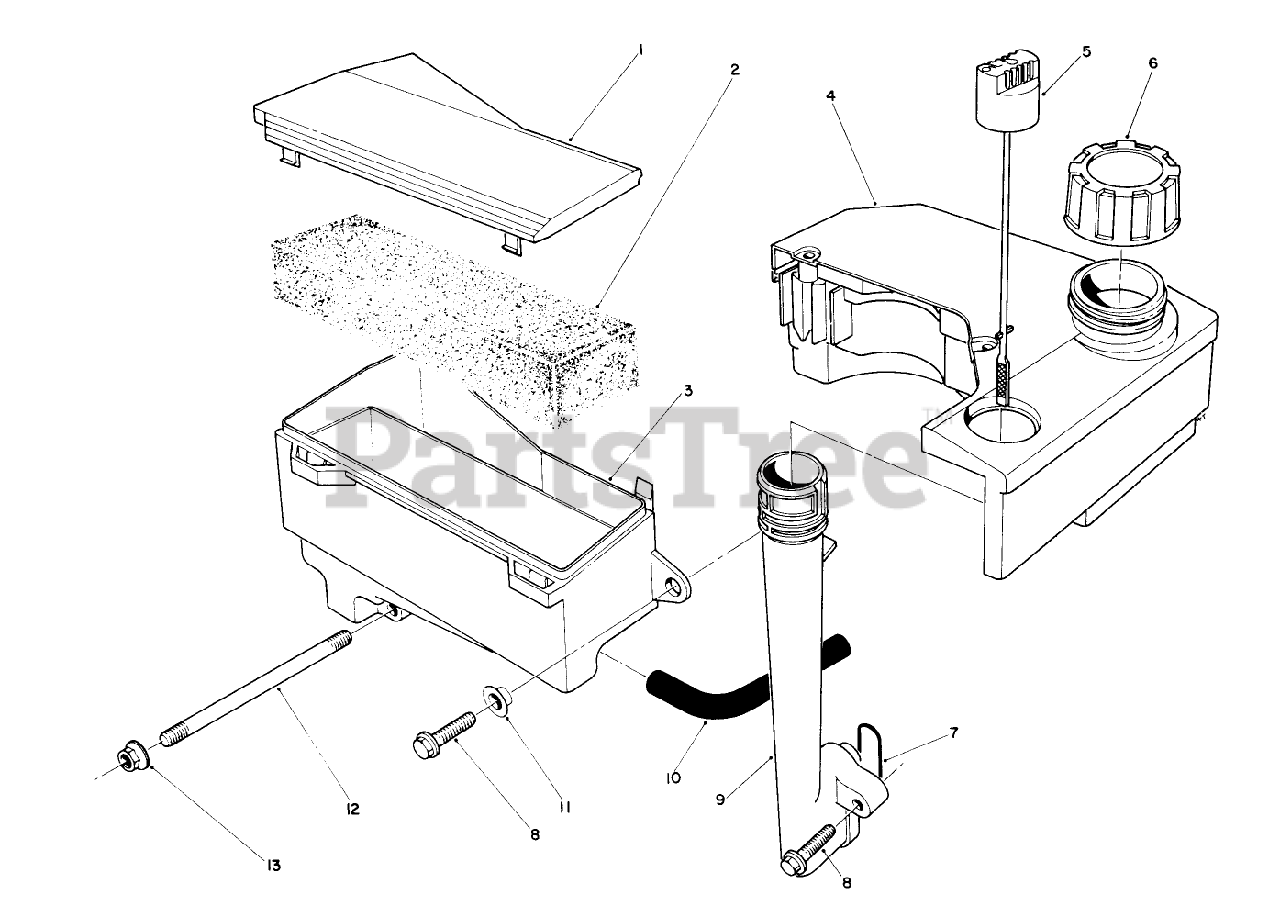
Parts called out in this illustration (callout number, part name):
1	AIR CLEANER CAP
3	Body-Air Cleaner
4	TANK ASM
6	GAS CAP ASM
7	O-RING
11	SPACER
